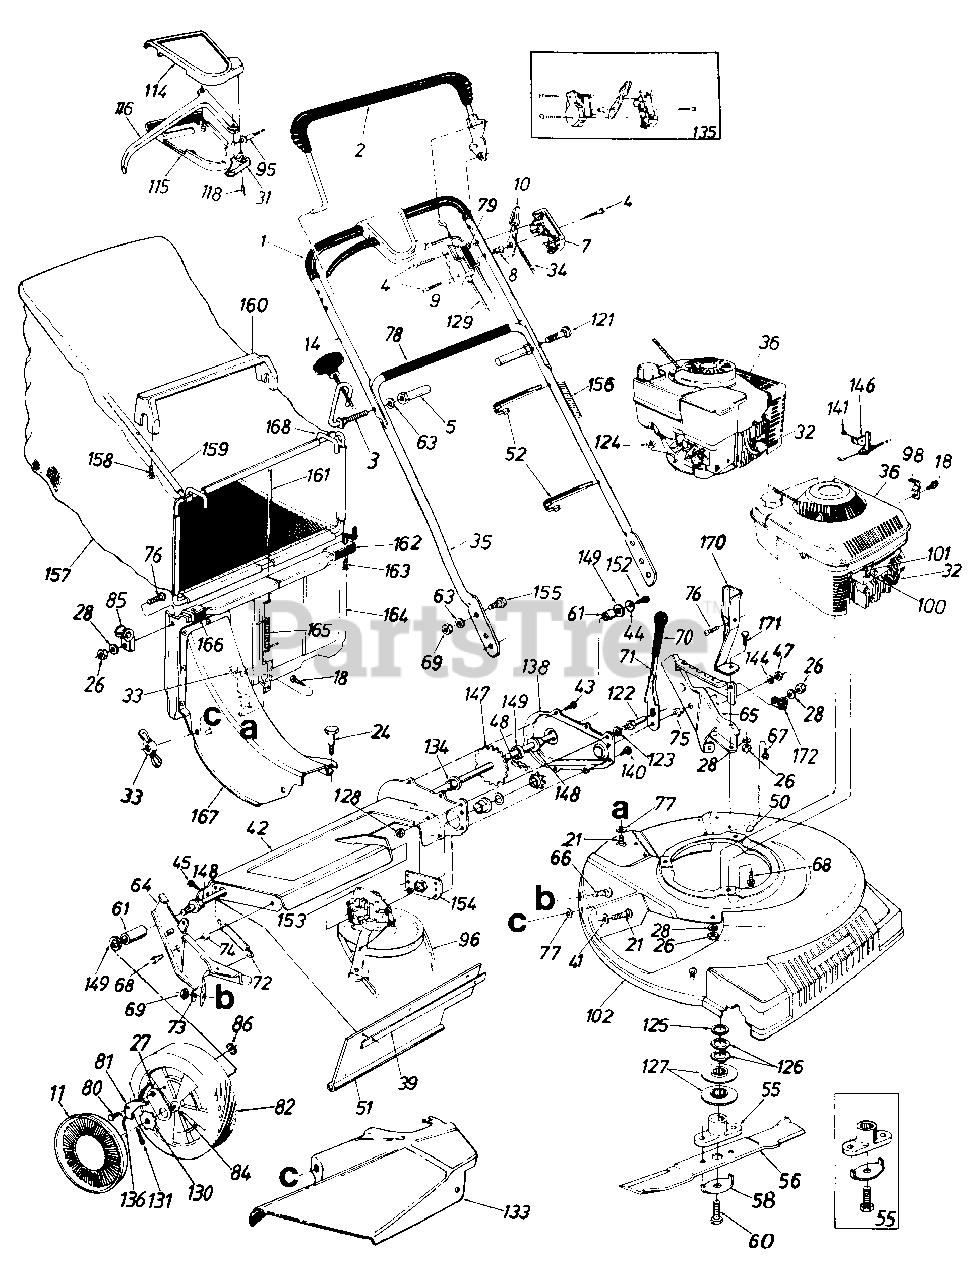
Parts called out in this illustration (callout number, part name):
1	Grip
2	Control Handle Ass'y. L.H.
3	Rope Guide Bolt
4	Truss Mach. Scr. #12 x 1.50" Lg.
5	Catcher Support Pint
7	Control Panel Half
8	Control Disc Pin
9	Clutch Panel Half
10	Throttle Control Lever
11	Hub Cap
14	Upper Handle
18	Hex B-Tap Scr. #10 x .38"
21	Carriage Bolt 1/4-20 x .62"
24	Shoulder Bolt Special
26	Hex Nut 1/4-20 Thd.
27	Pawl Plate
28	L-Wash. 1/4" I.D.
31	S.P. Control Cover
32	Spark Plug Insulator
33	Wing Nut
34	Throttle Control Wire 58"
35	Lower Handle
36	Engine
39	Retaining Strip
41	Fl-Wash. .344" I.D. x .62"
44	Bell-Wash. 1/4" I.D.
45	Hex AB-Tap Scr. 1/4 X .62"
47	Hex Patch L-Nut 3/8-24 Thd.
48	#48 Chain .500" Pitch x 30 Links
51	Rear Flap 3.75" x 17.30" Lg.
52	Cable Tie
55	Blade Adapter Kit
56	21" Blade
58	Blade Bell-Wash. .45" I.D.
60	Hex Bolt 7/16-20 x 1.5"
61	Spacer .513" I.D.
63	L-Wash. 5/16" I.D.
64	R.H. Handle Wheel Brkt. Ass'y.
65	L.H. Handle Wheel Brkt. Ass'y.
66	Carriage Bolt 5/16-18 x .62"
67	Hex Wash. Hd. B-Tap Scr. 5/16-18
68	Hex Wash. Hd. TT-Tap Scr. 3/8-1 6
69	Hex Nut 5/16-18 Thd.
71	Height Adj. Lever
72	Extension Spring 3.80" Lg.
73	Bell-Wash. 5/16" I.D.
74	Spacer.383" I.D.
75	Shld. Spacer .5" Dia.
76	Truss Mach. Scr. 1/4-20 x .5" Lg.
77	Bolt Retainer 1/4 x .50" O.D.
78	Instruction Label
79	Control Label
80	Shld. Scr. .342" Dia. x .268
81	Pawl
82	Wheel Ass'y. Comp. Rear
84	Sleeve Bearing 1/2" I.D.
85	Rope Guidet
86	Flat Nut 1/4-20 Thd.
95	S.P. Cable 50" Lg.
96	"V"-Belt
98	Casing Clamp
100	Hex B-Tap Scr. #10 x .62"
101	Casing Clamp
115	Self-Propelled Control Cover
116	Control Lever
118	FI-"C"-Sunk Hd. Tap Scr. #10 x .75" Lg.
121	Curved Carr. Bolt 5/16-18 x 1.75" Lg.
122	Shld. Pin 1.43" Lg.
123	L-Wash. 3/8" I.D.
124	Hex Nut 3/8 x 16 Thd.
125	Serrated Wash. 1.0" I.D.
126	Wave Wash. 1.005" I.D.
127	Serrated Pulley Half
128	Hex Jam Nut 3/8-24 Thd.
129	Control Cable 46"
130	Ratchet Wheel 1.62" O.D.
131	Cotter Pin 1/8" Dia. x 1"
133	Side Chute Deflector Ass'y.
134	Hex Flange Bearing
135	Kit Control Housing Comp.
136	Spring Nylon
141	Pop Rivet
144	Fl-Wash. .385" I.D. x .87"
146	Cable Bracket
147	Rear ShaH Ass'y. 21.94" Lg.
148	Hex Flange Brg. .506" I.D.
149	Fl-Wash. .531 " I.D. x .930"
152	Hex Bolt 1/4-20 x .62" Lg. (Grade 5)
153	Transmission Comp.
154	Hex Bearing Cup
155	Truss Mach. Scr. 5/16-18 x .75" Lg.
156	Plastic Tubing
157	Grass Bag
158	Hex AB-Tap Scr. #12 x 1.25" Lg.
159	Rear Catcher Frame
160	Bag Handle
161	Chute Rod .188" Dia.
162	Door Clip
163	Hex AB-Tap Scr. 1/4 X 75"
164	Chute Door
165	Torsion Spring
166	Panel Clip
167	Top Discharge Chute Ass'y.
168	Front Catcher Frame
170	Grass Catcher Brakcet
171	Hex Bolt 1/4-20 x .5" Lg.
172	Clamp
